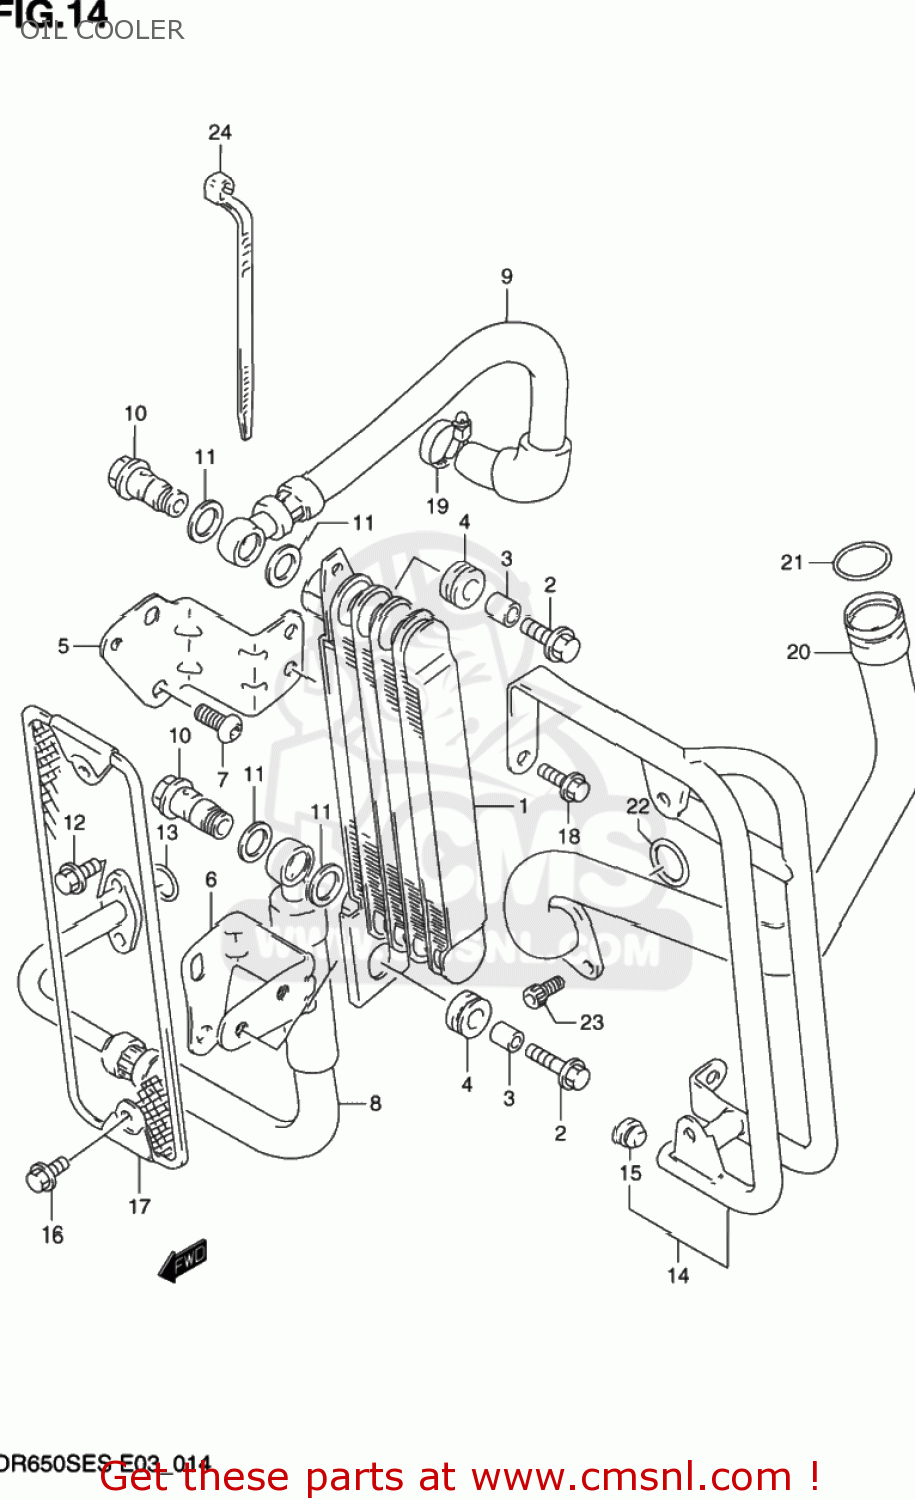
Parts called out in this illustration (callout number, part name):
1	COOLER ASSEMBLY,OIL
2	BOLT 6X20
3	SPACER (6.8X10X10)
4	CUSHION
5	BRACKET,OIL COOLER UPR
6	BRACKET,OIL COOLER,LOWER
7	BOLT(8X12)
8	HOSE,OIL COOLER NO.1
9	HOSE,OIL COOLER NO.2
10	BOLT UNION
11	GASKET(14X20X1.5) (NAS)
12	BOLT
13	O RING(D:2.4,ID:12.3)
14	GUARD,OIL COOLER
15	PLUG(OD:13)
16	BOLT
17	BUMPER,OIL COOLER
18	BOLT
19	CLAMP
20	PIPE COMP,OIL RETURN
21	O RING(D:3.7,ID:21.7)
22	O RING(D:2.4,ID:23.7)
23	BOLT
24	CLAMP(L:125)
